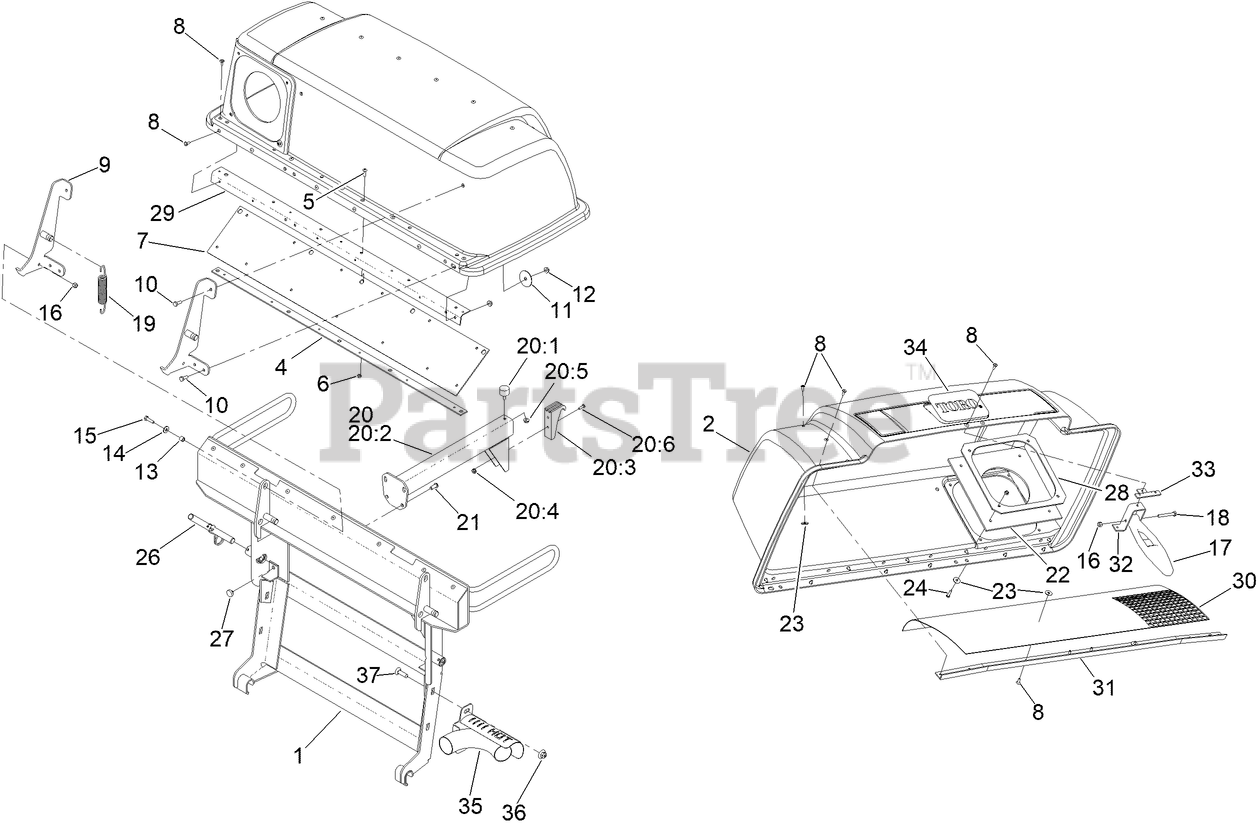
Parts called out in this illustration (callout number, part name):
1	FRAME-BAG, TWIN
2	HOOD ASM
4	PLATE-BACKING
5	SCREW-HEAD, TRUSS
6	NUT-LOCK, NI
8	RIVET-BLIND
9	HINGE ASM
10	SCREW-HH
11	WASHER
12	NUT-HF
13	SPACER
14	WASHER-FLAT
15	SCREW-HH
16	NUT-LOCK, NI
18	SCREW-HH
19	SPRING-EXTENSION
20	BAG SUPPORT ASM
20:1	BUMPER
20:2	SUPPORT-BAG
20:4	NUT-HF
20:5	NUT-HF
20:6	SCREW-PPH
21	SCREW-HSBH
22	SEAL-CHUTE
23	WASHER-FLAT
24	SCREW-PPH
26	PIN-MOUNT, BAGGER
27	BUMPER
28	CLAMP-SEAL
29	STIFFENER-BAGGER, TOP
30	SCREEN-BAGGER
31	SUPPORT-SCREEN
32	ANCHOR-LATCH
33	REINFORCEMENT-LATCH
34	DECAL
35	EXHAUST DIVERTER ASM
36	NUT-FLANGE, NI
37	SCREW-CARR
